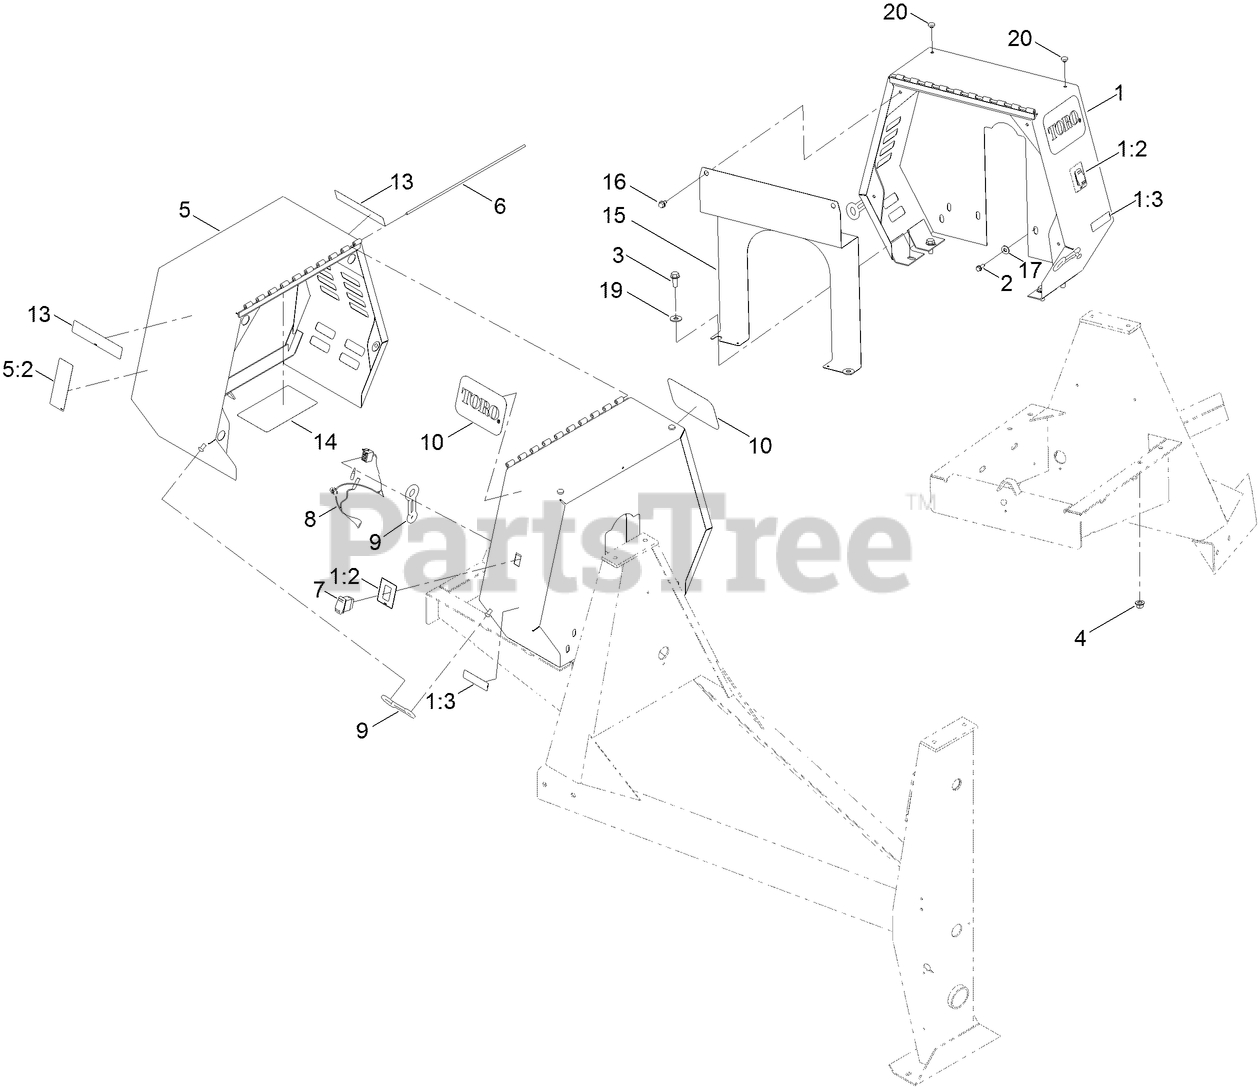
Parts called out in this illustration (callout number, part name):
1	STATIONARY COWL ASM
1:2	DECAL-STOP, ENGINE
1:3	DECAL-ARRESTOR, SPARK
2	SCREW-THD ROLL, HWH
3	SCREW-HHF
4	NUT-LOCK
5	MOVABLE COWL ASM
5:2	DECAL-WARNING
7	SWITCH
8	HARNESS-WIRE, MIXER
9	LATCH-RUBBER
10	DECAL
14	DECAL-SERVICE
15	PLATE-ENGINE
16	SCREW-HWH
17	WASHER-FLAT
19	WASHER-FLAT
20	BUMPER
